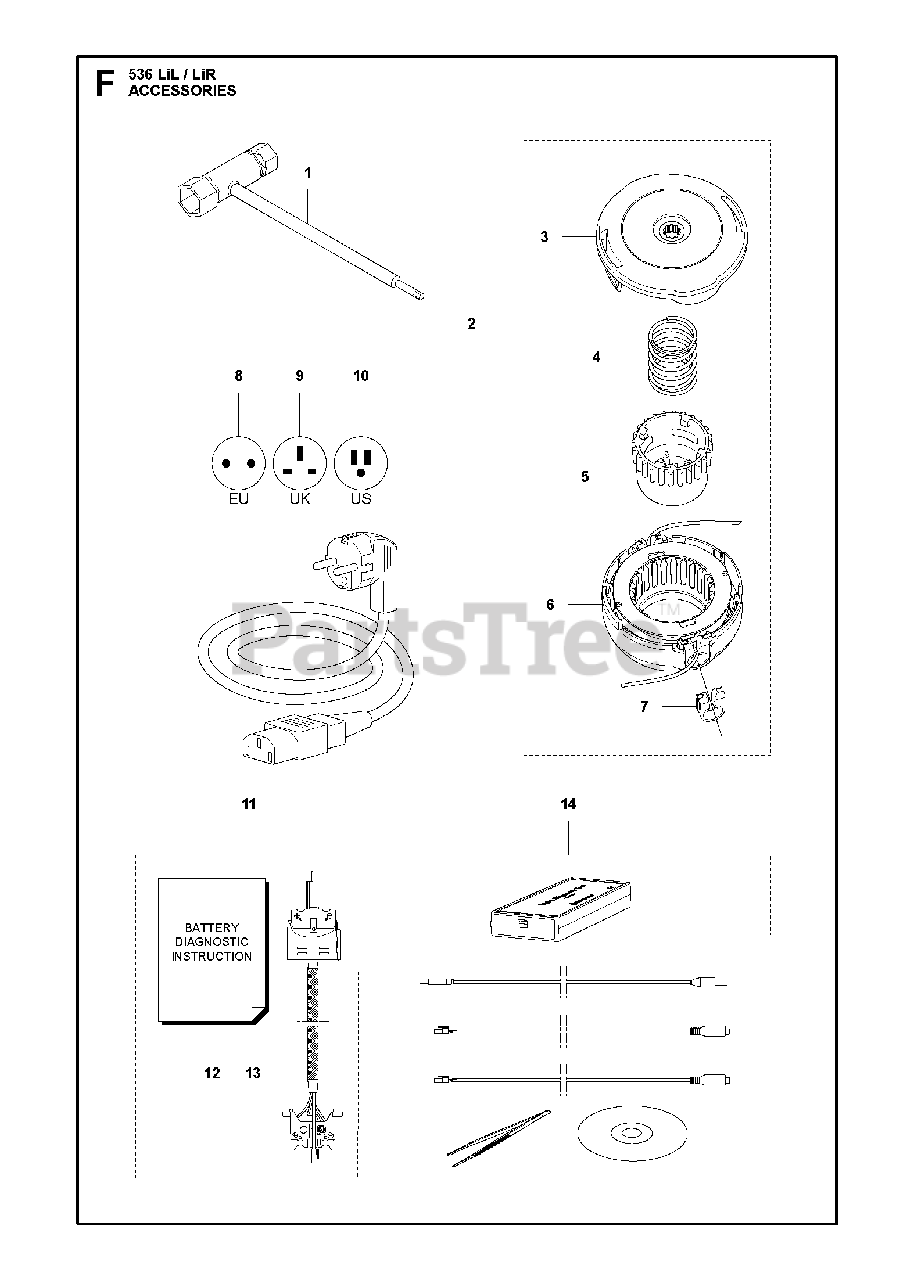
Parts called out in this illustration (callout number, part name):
1	COMB.TOOL 8-10-14
2	Trimmer Head, T25 10mm
3	HOUSING ASSY
4	SPRING
5	KNOB
6	COVER
8	MAIN CABLE
11	DIAGNOSTIC TOOL
13	WIRING ASSY
14	SERVICE TOOLS
